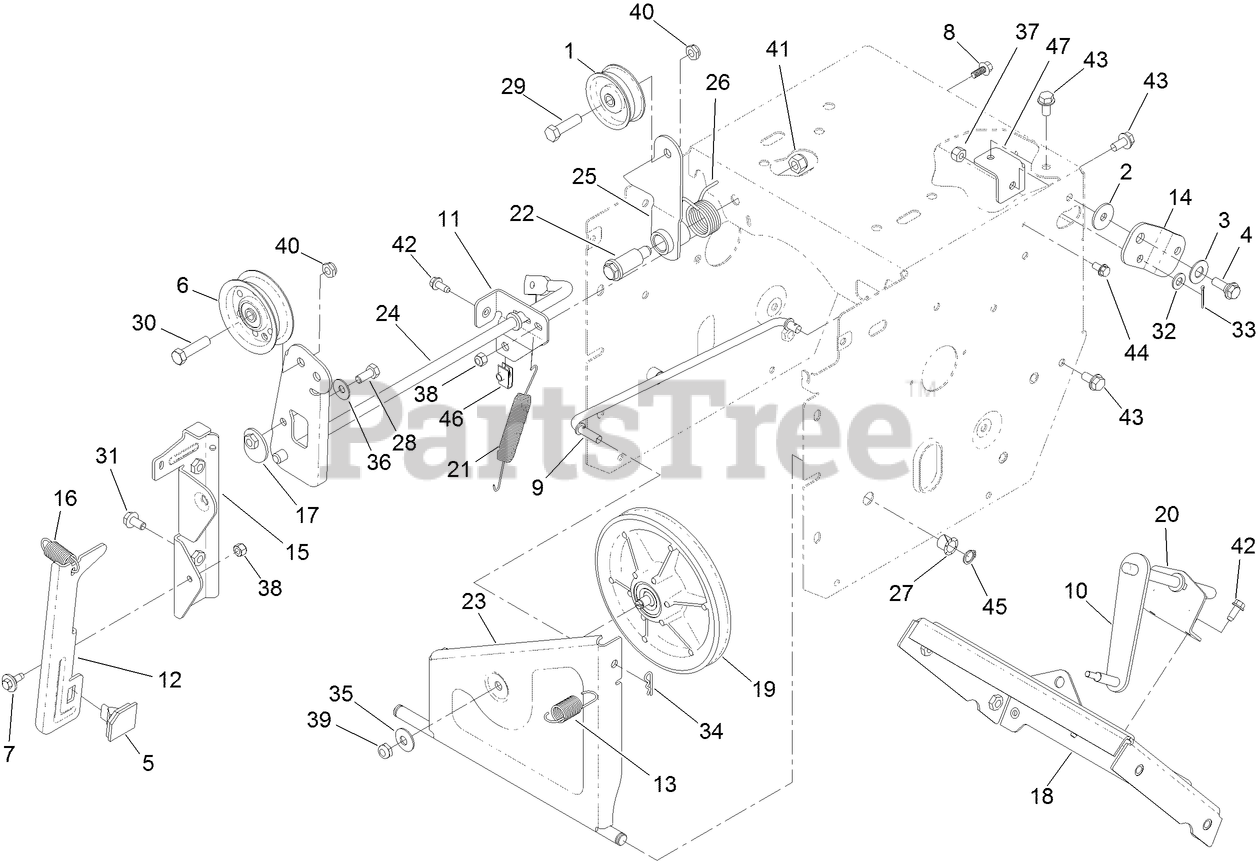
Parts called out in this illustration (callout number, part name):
1	PULLEY-IDLER
2	WASHER-PIVOT
3	WASHER
4	SCREW-SHOULDER
5	PAD-BRAKE
6	PULLEY-IDLER
7	SCREW-SHOULDER
8	SCREW-HHF
9	LINK-SPEED, CONTROL
10	TRACTION LEVER ASM
11	BRACKET-IMPELLER, CLUTCH
12	ARM-BRAKE
13	SPRING-EXTENSION
14	BELLCRANK
15	BRACKET-IMPELLER, IDLER
16	SPRING-EXTENSION
17	NUT ASSEMBLY
18	SHIFT PLATE ASM
19	PULLEY-TRACTION ASM
20	BRACKET-SHIFT, ROD
21	SPRING-EXTENSION
22	BOLT-SHOULDER
23	BRACKET-WHEEL, FRICTION
24	IMPELLER CLUTCH ASM
25	ARM-IDLER, TRACTION
26	SPRING-TORSION
27	BUSHING-NYLINER
28	SCREW-HH
29	SCREW-HH
30	SCREW-HH
31	SCREW-HHF
32	WASHER-PLAIN
33	PIN-COTTER
34	PIN-HAIR
35	WASHER-BELLEVILLE
36	WASHER-BELLEVILLE
37	NUT-HEX
38	NUT-HEX
39	NUT-HEX
40	NUT-HEX
41	NUT-HEX
42	SCREW-HWH
43	SCREW-HWHTF
44	SCREW-HWH
45	RING-RETAINING
